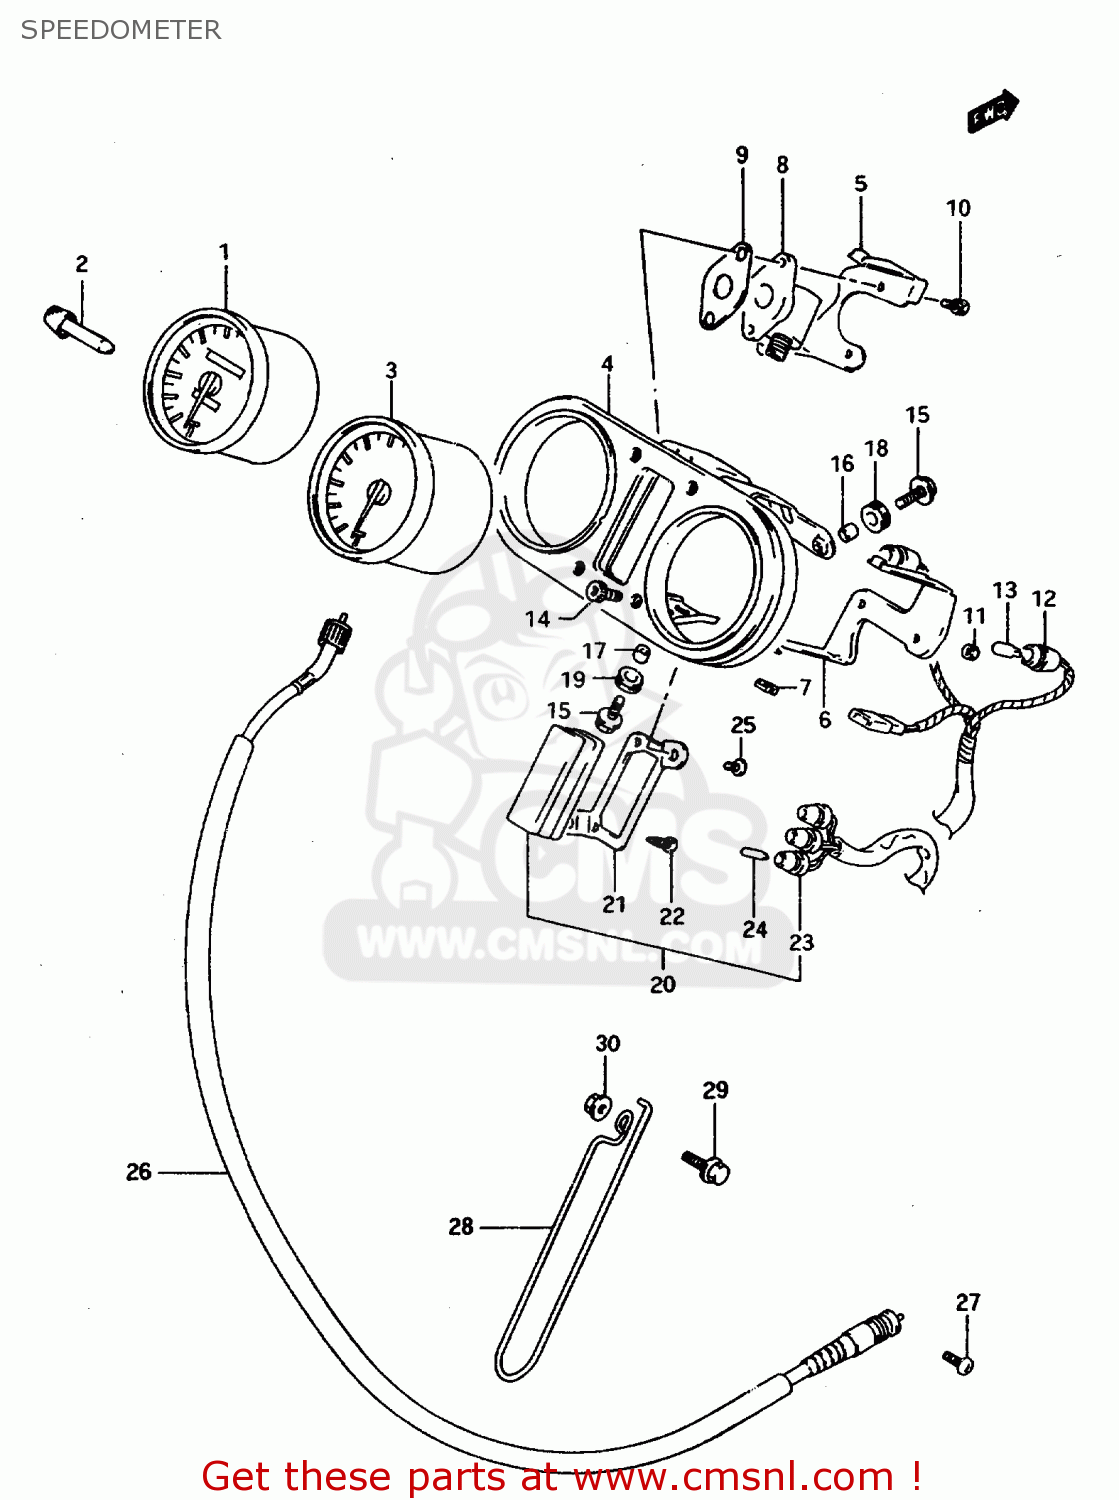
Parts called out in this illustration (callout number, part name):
1	SPEEDOMETER(KILO)
2	KNOB,TRIP
3	TACHOMETER
4	PANEL, METER
5	BRACKET,SPEEDOMETER
6	BRACKET, TACHOMETER
7	DAMPER
8	GEAR BOX
9	GASKET,METER GEAR BOX (NAS)
10	SCREW
11	NUT
12	SOCKET
13	BULB(12V3W,T6.5)
14	BOLT
15	BOLT 6X20
16	SPACER(6.5X9X10.5)
17	SPACER(6.1X8X9.5)
18	CUSHION
19	CUSHION
20	BOX ASSY, PILOT LAMP
21	BRACKET,PILOT BOX
22	SCREW, OUTER
23	SOCKET
24	BULB(13.5V,2W,A7427)
25	SCREW
26	CABLE ASSY,SPEEDOMETER
27	SCREW
28	GUIDE,METER CABLE NO.2
29	BOLT(6X20)
30	NUT
